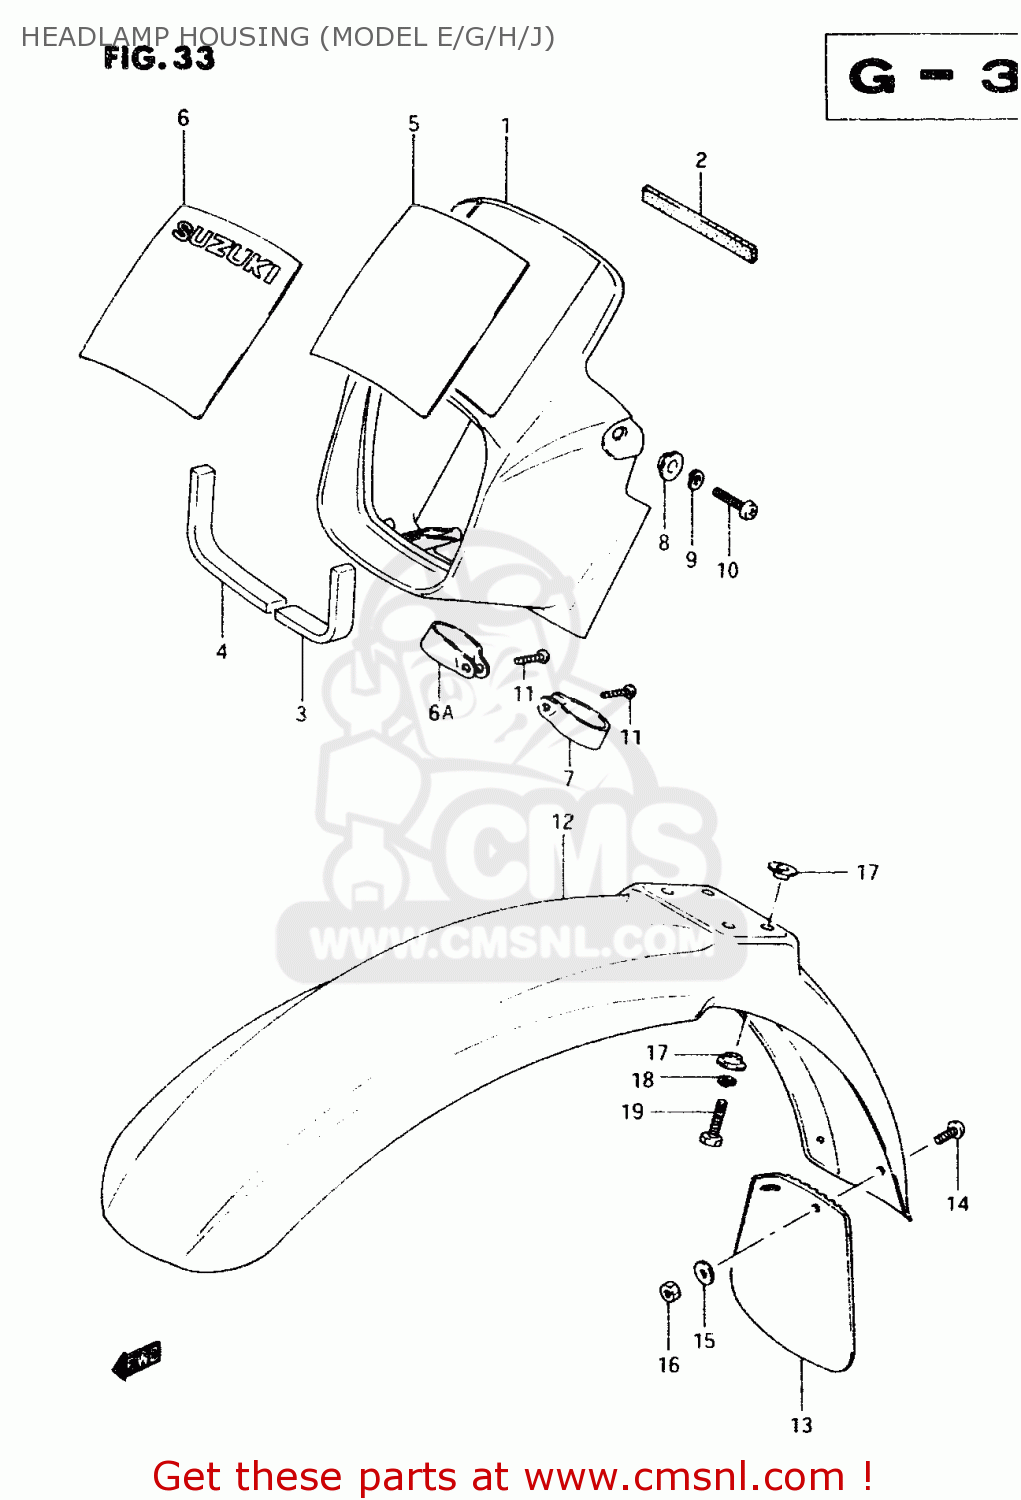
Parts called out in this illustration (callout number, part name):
1	HOUSING HEAD L
2	CUSHION,HEADLAMP HOUSING
3	CUSHION,HEADL.
4	CUSHION,HEAD L
5	EMBLEM
6	EMBLEM
6A	CLAMP,HEADLAMP HOUSING,R
7	CLAMP, HEADLAMP HOUSING, LH
8	WASHER
9	WASHER,LOCK
10	SCREW
11	SCREW
12	FENDER,FR
13	MUD FLAP,FRONT FENDER
14	SCREW
15	WASHER
16	NUT
17	WASHER
18	WASHER,LOCK
19	BOLT
